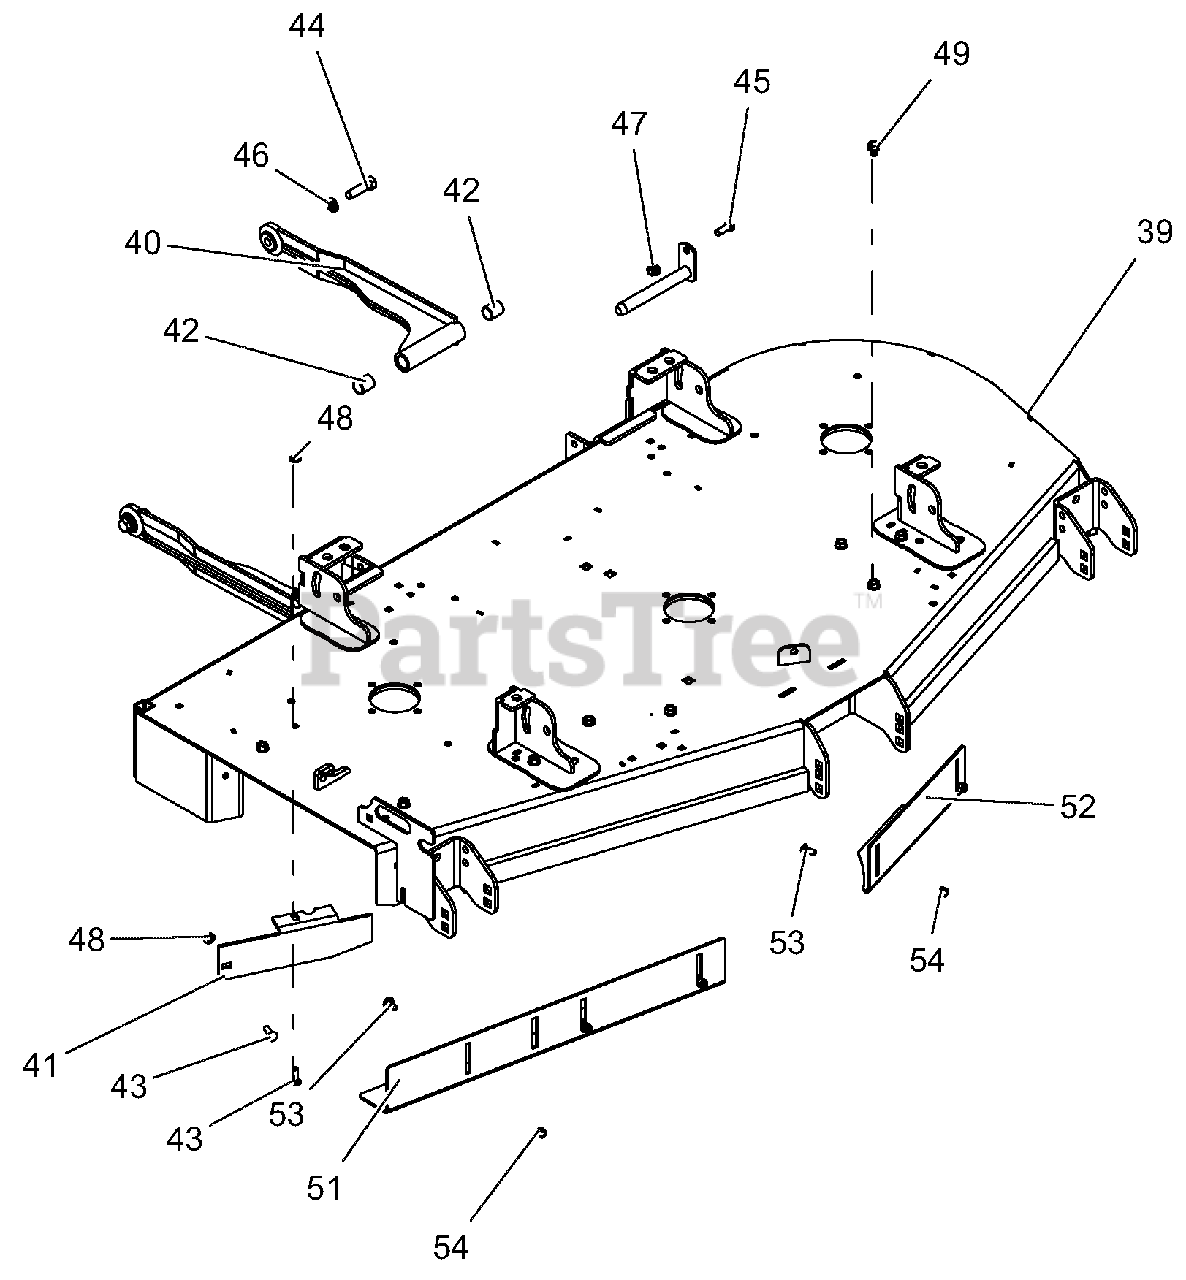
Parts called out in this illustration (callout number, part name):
39	WLDMT, 60" SIDE DISCH DECK
40	WMT, DECK STABILIZER ARM-BLACK
41	BAFFLE, 60" DISCHARGE
42	BRG, .75 X .875 X 1.00
43	BLT-RDHDSQSHNK .31-18X1.00 G5 Y
44	BLT-HEX .50-13X1.75 GR5 YWZC
45	BLT-HEX .38-16X1.00 GR5 YWZC
46	WSHR-LK .50X.125 REG YWZC
47	NUT-LK-NYL-FLG .38-16 YWZC
48	NUT-LK-NYL-FLG .31-18 YWZC
49	SCR-TAP .38-16X.50 HWH TR YWZ
51	BAFFLE, 60" RH VACUUM
52	BAFFLE, 60" LH VACUUM
53	BLT-RDHDSQNK .31-18X.75 G5 YWZC
54	NUT-LK-NYL .312-18 YWZC
